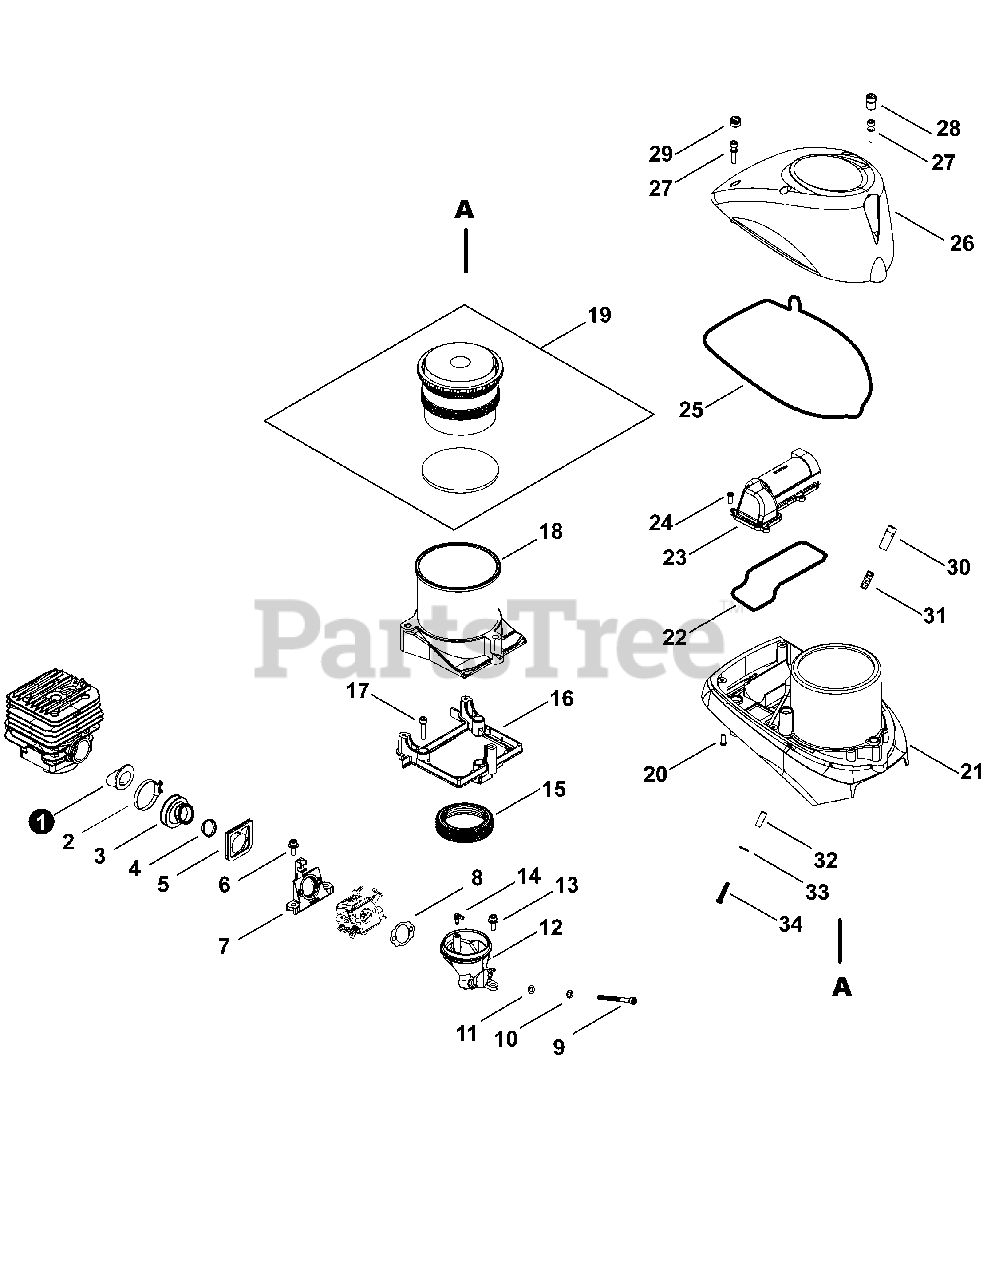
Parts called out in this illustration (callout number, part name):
1	PIPE, INTAKE
3	BELLOWS, INTAKE
4	SLEEVE 18
7	INSULATOR, INTAKE
8	GASKET, INTAKE
9	BOLT 5×60
10	WASHER, SPRING 5 MM
11	WASHER, FLAT 5.5×10×0.8
12	ELBOW, CARBURETOR
14	CONNECTOR, PIPE
16	SUPPORT, FILTER
17	BOLT M5×25
18	CASE ASSY, AIR FILTER
19	AIR FILTER KIT
20	SCREW 4
21	COVER, AIR FILTER
22	SEAL, CLEANER
23	COVER, AIR FILTER
24	SCREW 4
25	SEAL, CLEANER
26	COVER, CYLINDER
28	GROMMET, PLUG
29	GROMMET, PLUG
30	SHAFT, DECOMPRESSSION
31	SPRING, COMPRESSION
33	WASHER 5.5×12×0.8
34	SCREW 5
